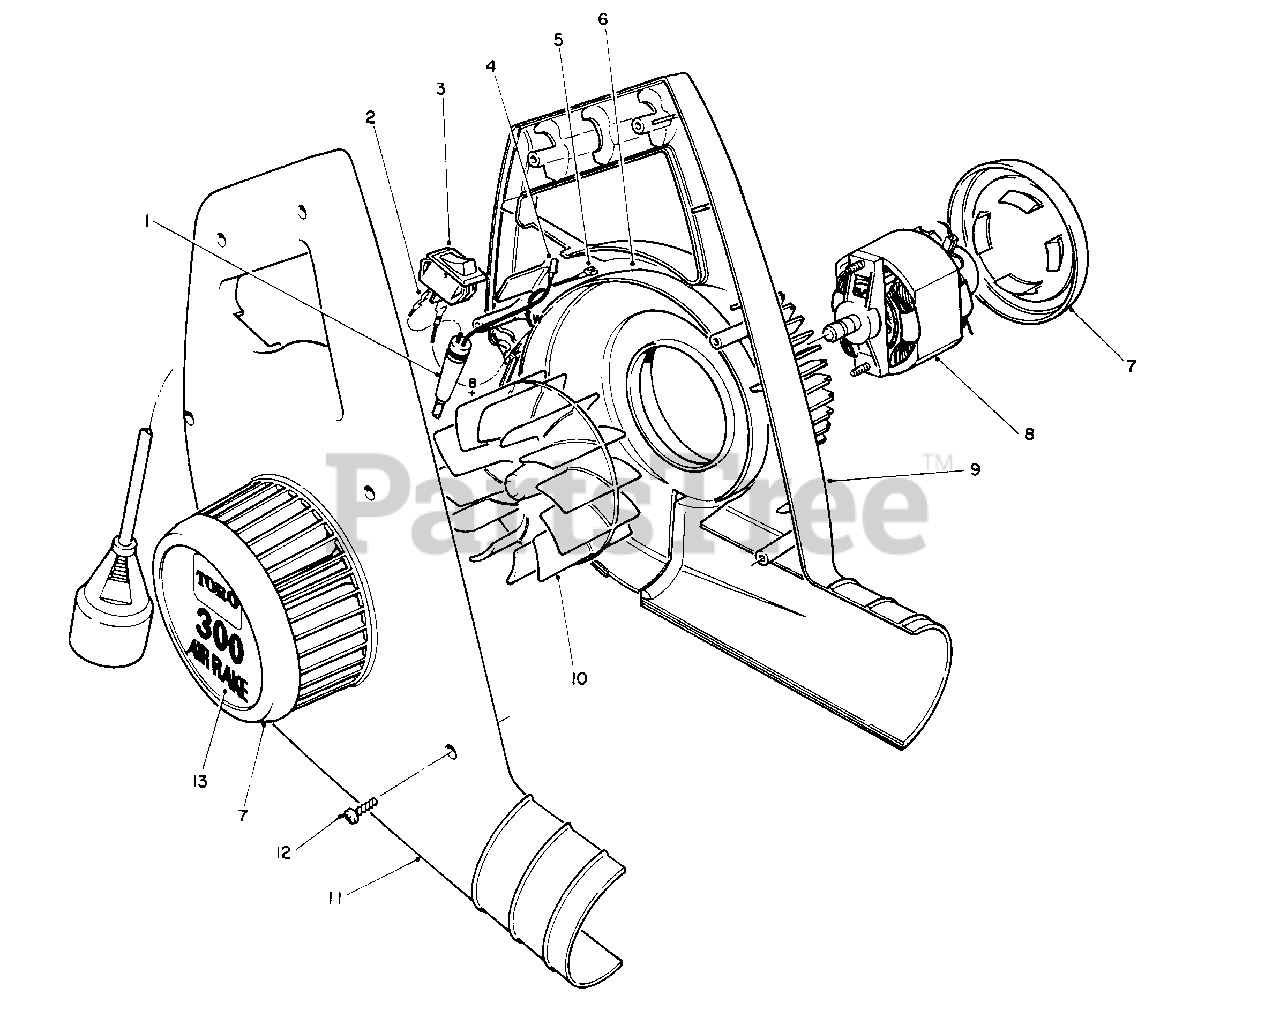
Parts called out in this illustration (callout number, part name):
1	Cord-Power Supply
2	Terminal-Female
4	Coupler-Quick Disconnect Male
5	Coupler-Female Quick Disconnect
6	Cover-Motor
7	Cover-Intake
8	Motor-120 Volt
9	Housing-L.H.
10	Impeller
11	Housing-R.H.
12	Screw-Thread Forming
13	Decal-300
